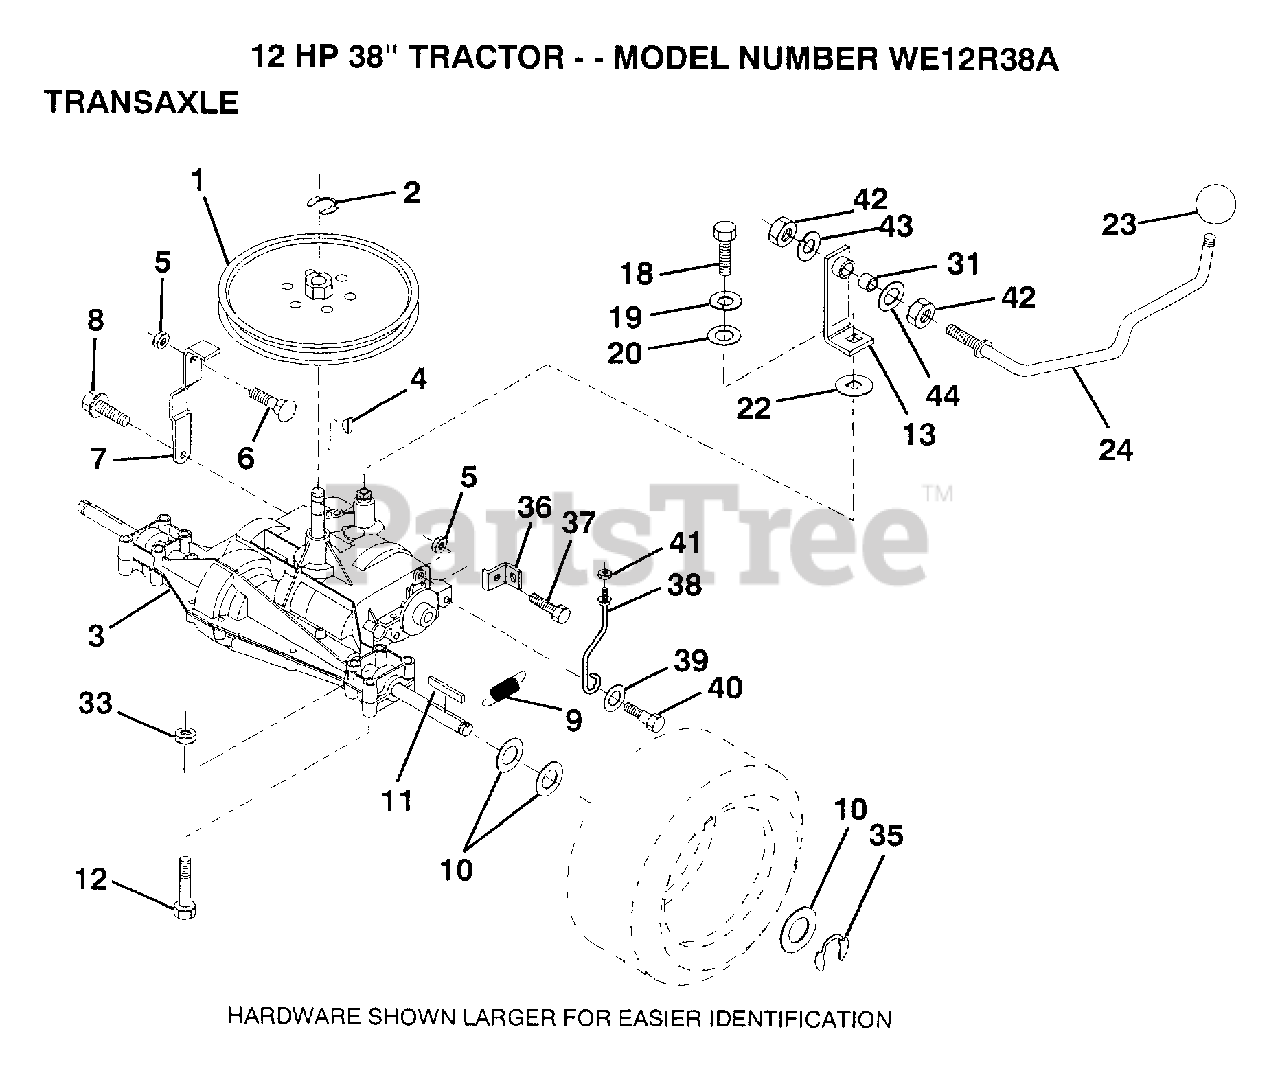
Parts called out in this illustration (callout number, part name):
1	PULLEY
3	TRANSAXLE.6SP.DAN
6	BOLT
7	STRAP.TORQUE.LH
8	SCREW
10	WASHER
11	SQUARE KEY
12	BOLT
13	BRACKET.ASM.SHIFT
19	LOCKWASHER
20	WASHER LT
22	WASH-SHFT PLT LT
23	KNOB T (1/2-HOLE)
24	ROD.SHIFT.CNTR.LR
35	E-RING LT
36	BRACKET.BRAKE
37	BOLT
38	KEEPER.BELT.RH
40	BOLT SHD 5/16-18
41	NUT
42	NUT
43	LOCKWASHER
44	WASHER
